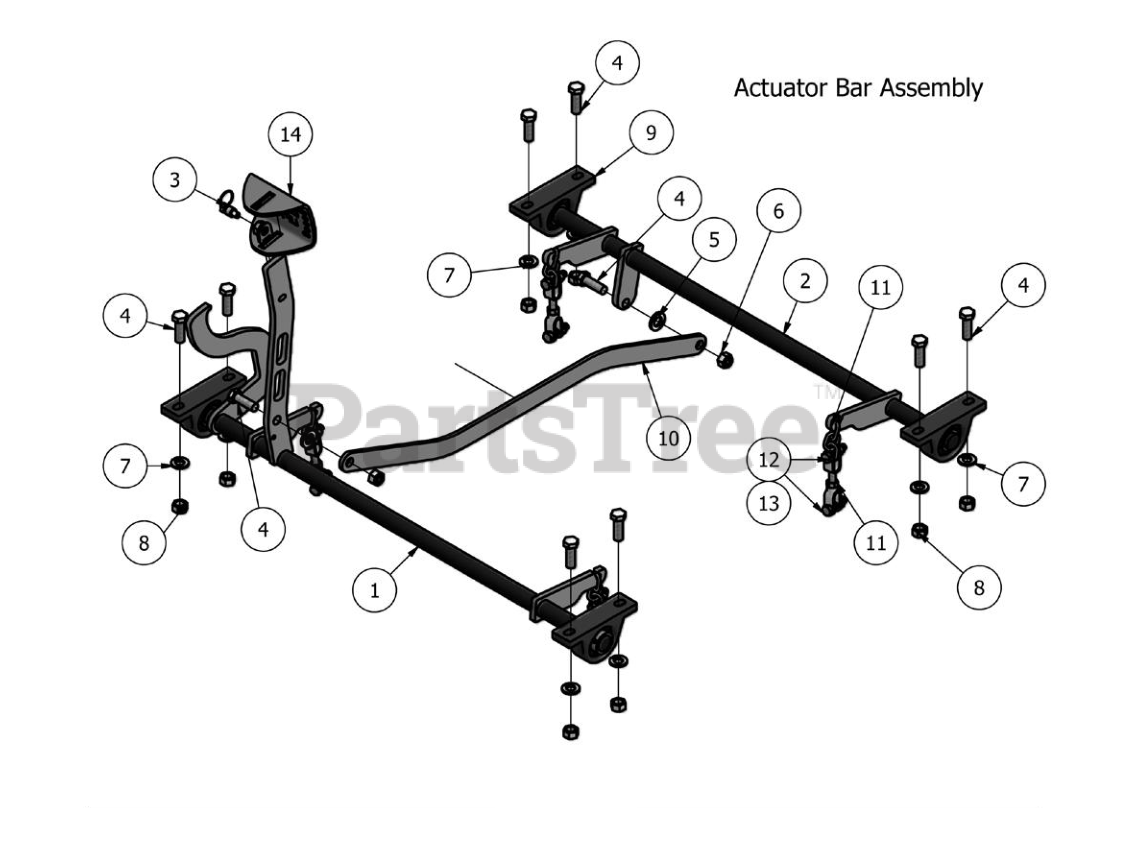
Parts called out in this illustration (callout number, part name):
1	Outlaw Front Actuator Bar Assembly
2	Outlaw rear Actuator Bar Assembly
4	1/2-20 x 1-1/2 Grade 5 Hex Bolt Zinc
5	.630 ID X 1.122 OD X .142 THK Flat Washer Nylon
6	1/2-12 Nylon Locknut Zinc Orange Nylon
7	1/2 Lock Washer Zinc
8	1/2-13 Hex Nuts Zinc
9	pillow block 2bolt sealmaster
10	Outlaw Deck Linkage Rod
11	Yoke/Deck Hanger Assby - 3 Link Chain
12	3/8-16 x 1/ 1/2 GR5 Hex Bolt
13	3/8-18 Nylon Insert Locknut Zinc Orange Nylon
14	Outlaw Deck Lift Pedal
